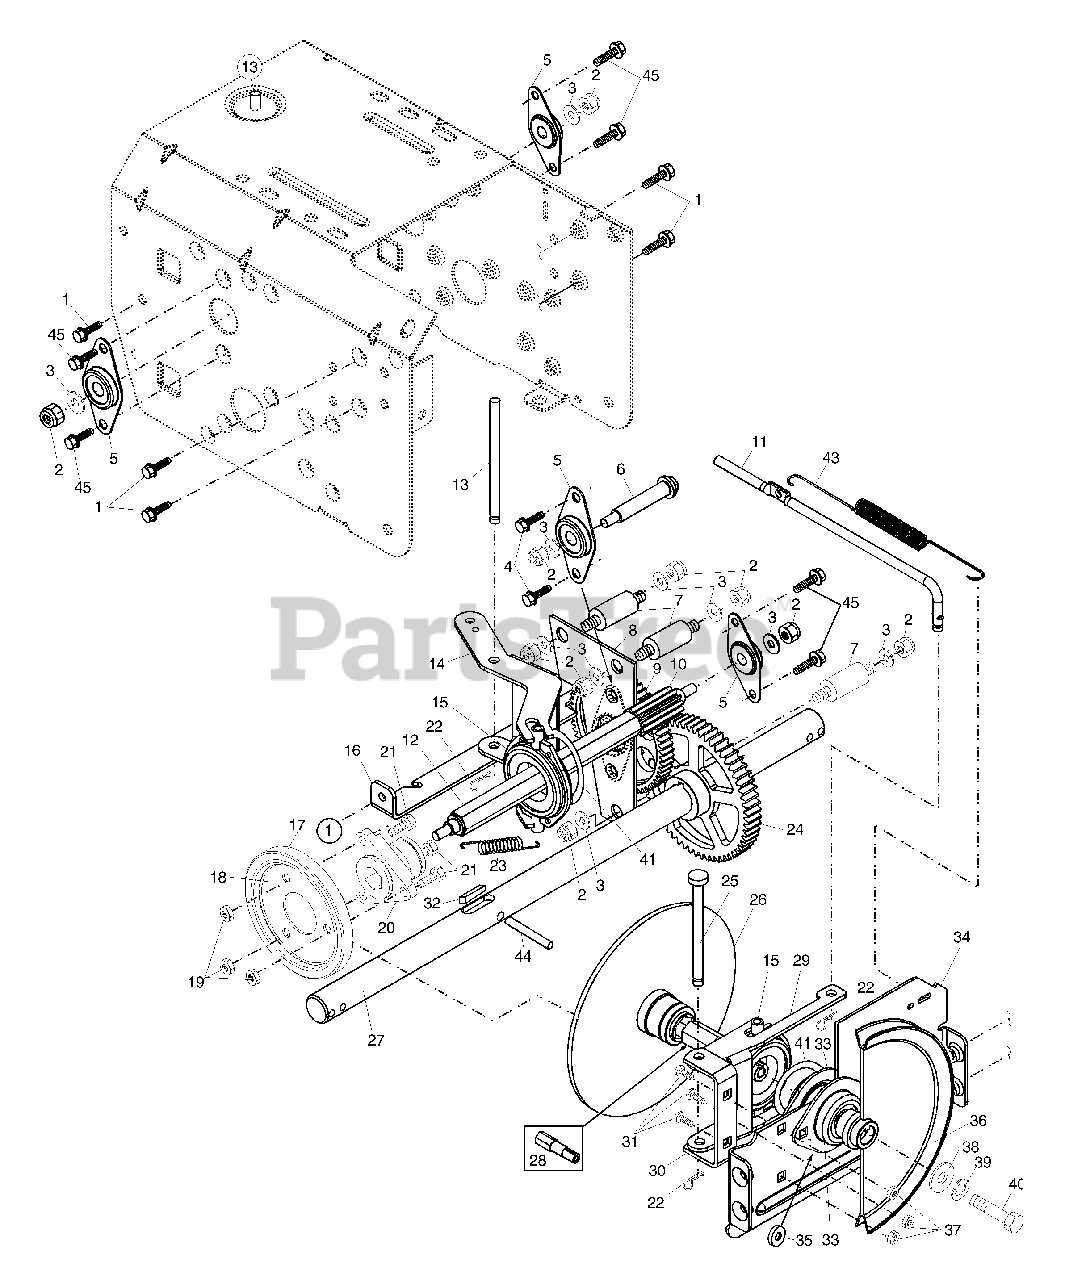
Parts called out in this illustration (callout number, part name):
1	Screw, Hex Head 5/16-18 x 3/4
2	Nut, Lock 5/16-18
3	Washer, Flat
4	Screw, Hex Head 5/16-18 x 1/2
5	Bearing, Flange
6	Shaft, Auxiliary
7	Spacer, Plate
8	Plate, Auxiliary
9	Gear, Intermediate (12/58)
10	Gear, Pinion
11	Rod, Clutch
12	Shaft, Long, Hex
13	Pin, Pivot
14	Lever, Shifter / Wheel
15	Trunnion Bearing Assembly
16	Bracket, Pivot, Shift
17	Ring, Rubber Wheel
18	Plate, Rubber Wheel
19	Nut, Lock 5/16-18
20	Hub, Rubber Wheel
21	Screw, Hex Head 5/16-18 x 7/8
22	Retainer, Hairpin
23	Spring, Bias
24	Gear, Axle (58 Teeth)
25	Pin, Pivot Lever
26	Plate Assembly, Drive
27	Shaft, Axle
28	Shaft, Short Hex
29	Lever, Shifter Plate
30	Bracket, Shifter Support
31	Bolt, Carriage 5/16-18 x 5/8
32	Key, Square 1/4 x 1/4 x 7/8
33	Bearing, Flange
34	Plate, Drive Mounting
35	Spacer, Bearing
36	Pulley, Traction Drive
37	Nut, Lock 5/16-18
38	Washer, Flat
39	Washer, Lock 5/16
40	Screw, Hex Head 5/16-18 x 3/4
41	Ring, Retaining
43	Spring, Return
44	Pin, Roll
45	Screw, Hex Head 5/16-18 x 3/4
